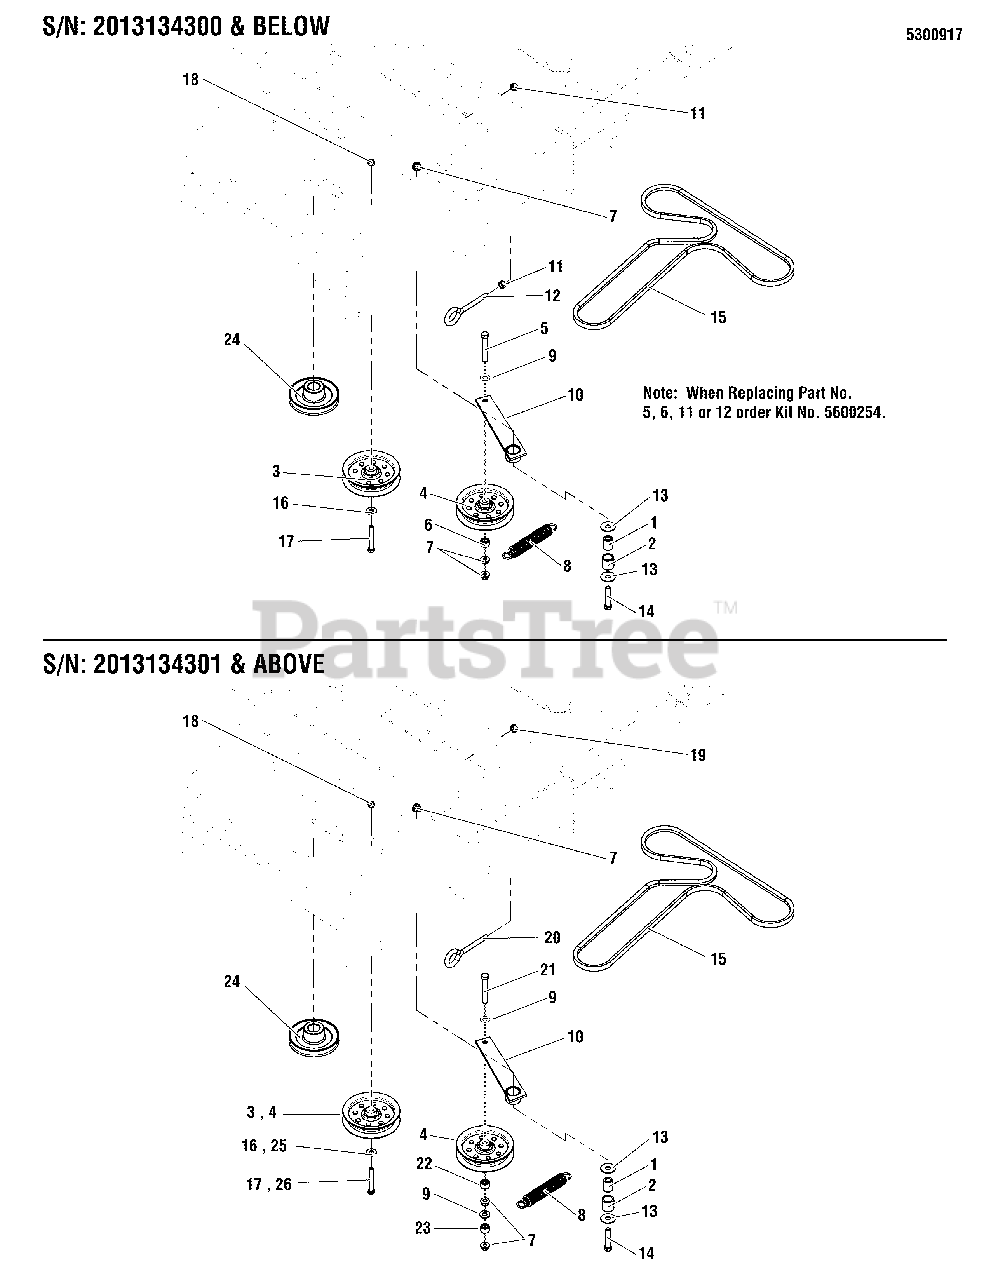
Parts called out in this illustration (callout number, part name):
1	SPACER, .38 X .75 X 1.06, YZ
2	BUSHING, BRASS, 3/4 X 1 X 1
3	PULLEY-IDLER, 4.06OD, .315ID, .75W STL
4	PULLEY-IDLER, 4.06OD, .375ID, .75W STL
5	BOLT, 3/8-16 X 2-3/4" GD5 CZ
6	SPACER, .39 x .75 x .50
7	NUT, 3/8 - 16 HEX NYLOCK FLANGE
8	SPRING, EXTENSION, 1.00
9	WASHER, 3/8 SAE
10	WELD, IDLER ARM, SNAPPER PRO - BLK
11	NUT, 5/16-18 HEX
12	EYE BOLT, 3/8-16 X 5, 2.88THRD, 1EYE, CZ
13	WASHER, 3/8" Fender
14	BOLT, 3/8-16 X 2, GD5, CZ
16	WASHER, 5/16" USS
17	BOLT, 5/16-18 X 2-1/2" GD5 YZ
18	NUT, Hex, Nylon Locking, 5/16-18
19	NUT, 5/16-18 HEX NYLOCK FLANGE NUT
20	EYE BOLT,5/16-18 X3.5,2.13THRD,.55EYE,CZ
21	BOLT, 3/8-16 X 3 GD5 TFL
22	SPACER, .39 X 1.00 X .50, PM, CZ
23	SPACER, .38 X .50 X .27, CZ
24	SEE ENGINE GROUP
25	WASHER, 3/8" USS
26	BOLT,HEX FLG,SER GD5 3/8-16X2, PATCH,CZ
